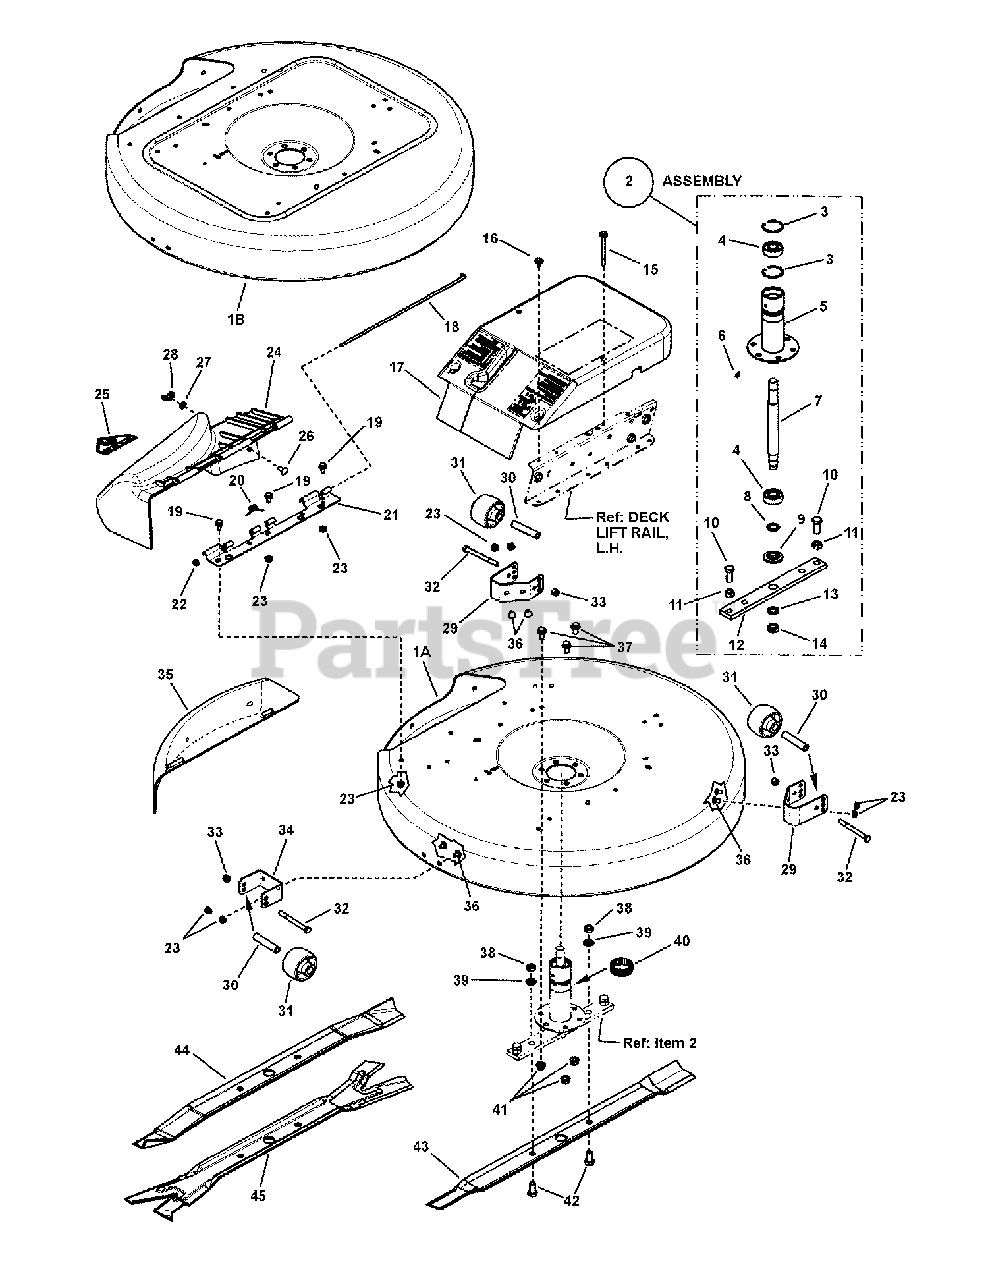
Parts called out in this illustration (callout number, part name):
1A	DECK, 28" Replacement (painted deck w/decals)
1B	DECK, 33" Replacement (painted deck w/decals)
2	ASSEMBLY, Spindle Housing (Incl. items 3 thru 14)
3	RING, 1.85" Internal Retaining
4	BEARING, Spindle
5	ASSEMBLY, Housing (Incl. grease fitting, 7010817)
6	LUBE FITTING, 3/16" Press-In
7	SPINDLE, Rider (10.327" overall length)
8	WASHER, .77 x 1.13 x .06 Flat
9	WASHER, Spindle
10	SCREW, 1/2-20 x 1-1/4" Hex Head Cap, GR 5
11	NUT, 1/2-20 Hex, GR 5 or B
11	HOLDER, Blade (for 25" deck)
12	HOLDER, Blade (for 28" Deck)
13	SPACER, Blade Centering
14	NUT, 5/8-18 Hex Center Lock Jam
15	SCREW, 1/4-20 x 3-1/2" Hex Head w/Free Spinning Washer
16	SCREW, 1/4-20 x 5/8" Hex Head w/Free Spinning Washer
17	COVER, Spindle
18	PIN, Hinge
19	BOLT, 5/16-18 x 5/8" Hex Flange Lock, GR 5
20	SPRING, Hinge
21	HINGE, Deflector (Deck side)
22	PUSH NUT, 1/4"
23	NUT, 5/16-18 Hex Flange Lock, GR 5
24	ASSEMBLY, Discharge Deflector, 25" & 28" (w/o decal)
24	DEFLECTOR, Discharge, 28"
25	DECAL, Danger, (Cut Finger) International Symbol
26	BOLT, 5/16-18 x 3/4" Short Neck Carriage, GR 5
27	WASHER, 5/16" Flat
28	NUT, 5/16-18 Wing
29	BRACKET, Gage Wheel (Rear)
30	SPACER
31	WHEEL, Gage
32	SCREW, 3/8-24 x 3-3/4" Hex Head Cap, GR 5
33	NUT, 3/8-24 Hex Nyloc
34	BRACKET, Gage Wheel (Front)
35	COVER, 28" Mulcher
35	COVER, 33" Mulcher
36	BOLT, 5/16-18 x 1/2" Short Neck Carriage, GR 5
37	BOLT, 3/8-16 x 3/4" Hex Flange Lock
38	NUT, 1/2-20 Hex Jam
39	WASHER, 1/2" Internal Tooth Lock
40	RING, Tolerance
41	NUT, 3/8-16 Hex Flange Lock
42	SCREW, 1/2-20 x 1" Hex Head Cap, GR 5
43	BLADE, 28" High Lift (No Air Lift Holes)(Standard Equipment)
43	BLADE, 33" High Lift (No Air Lift Holes)(Standard Equipmment)
44	BLADE, 28" Mulcher
44	BLADE, 33" Mulcher (No Longer Available, USE 7024741AYP)
45	BLADE, 28" Recycling Ninja
45	BLADE, 33" Ninja Mulcher
